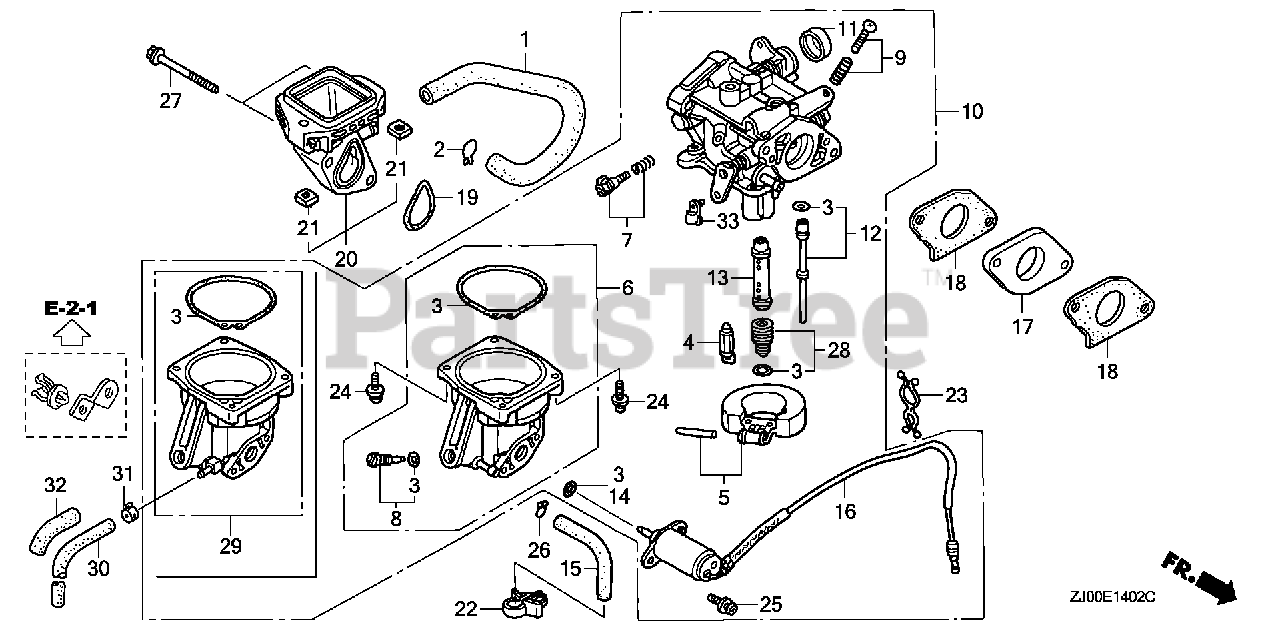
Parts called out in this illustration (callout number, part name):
1	TUBE, BREATHER
2	CLIP, BREATHER TUBE
3	GASKET SET (CARBURETOR NO.)
4	VALVE SET, FLOAT
6	CHAMBER SET, FLOAT (CARBURETOR NO.)
8	SCREW SET, DRAIN (CARBURETOR NO.)
10	CARBURETOR ASSY. (BG21H C)
11	CAP, CHOKE DUST
12	JET SET (#58)
13	NOZZLE, MAIN
14	O-RING (5.8X1.9) (CARBURETOR NO.)
15	TUBE, DRAIN
16	VALVE ASSY., SOLENOID
17	INSULATOR, CARBURETOR
18	GASKET, CARBURETOR
19	GASKET, AIR CLEANER
20	ELBOW, AIR CLEANER
21	NUT, INSERT (6MM)
22	CLIP B, CABLE (9MM BLACK)
23	CLIP, PURSE LOCK
24	SCREW-WASHER (4X14)
25	SCREW-WASHER (5X12)
26	CLIP, TUBE (B8)
27	BOLT, FLANGE (6X120)
28	JET SET, MAIN (#88)
28	JET SET, MAIN (#90)
28	JET SET, MAIN (#92)
33	ARM, THROTTLE LINKAGE
